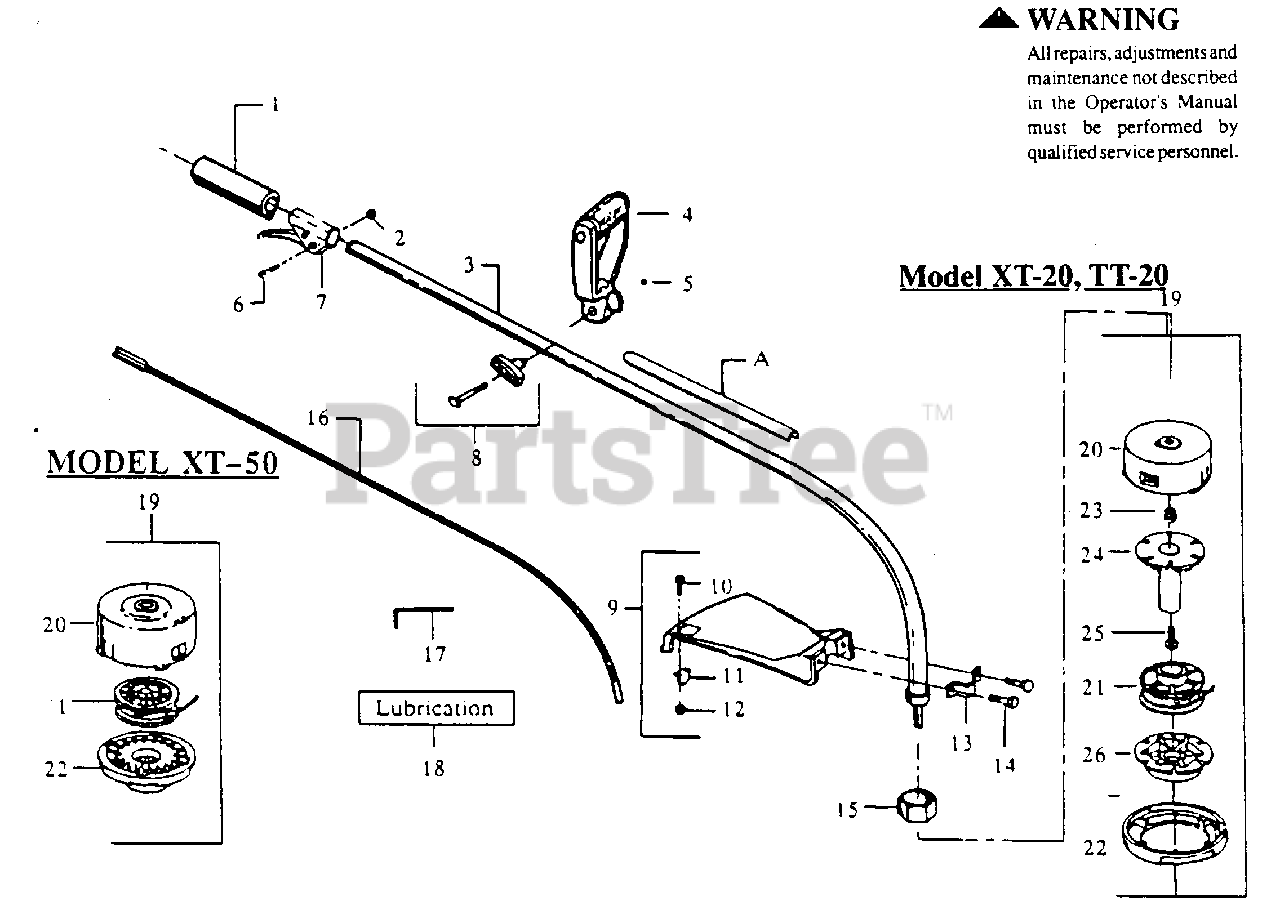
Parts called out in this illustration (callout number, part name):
1	Grip
3	Model XT-20,TT-20
3	Model XT-50
4	Handle Assy.
7	Throttle Housing Assy.
8	"T" Handle Kit
9	Shield Kit Assy. (Inc.10,11,12,14)
11	Line Limiter
12	Locknut
13	Shield Bracket
14	Screw
15	Dust Cap
16	Model XT-20,TT-20
16	Model XT-50
17	Hex Wrench (5/32)
18	Shaft Lubrication
19	Model XT-20,TT-20
19	Model XT-50
20	Model XT-20,TT-20
20	Model TT-50
21	Model XT-20, TT-20, TT-50
22	Model XT-20,TT-20
22	Model TT-50
23	Spring Model XT-20,TT-20
24	Spool Post Model XT-20,TT-20
25	Screw Model XT-20,TT-20
26	Release Button Model XT-20,TT-20
A	Warning Decal
